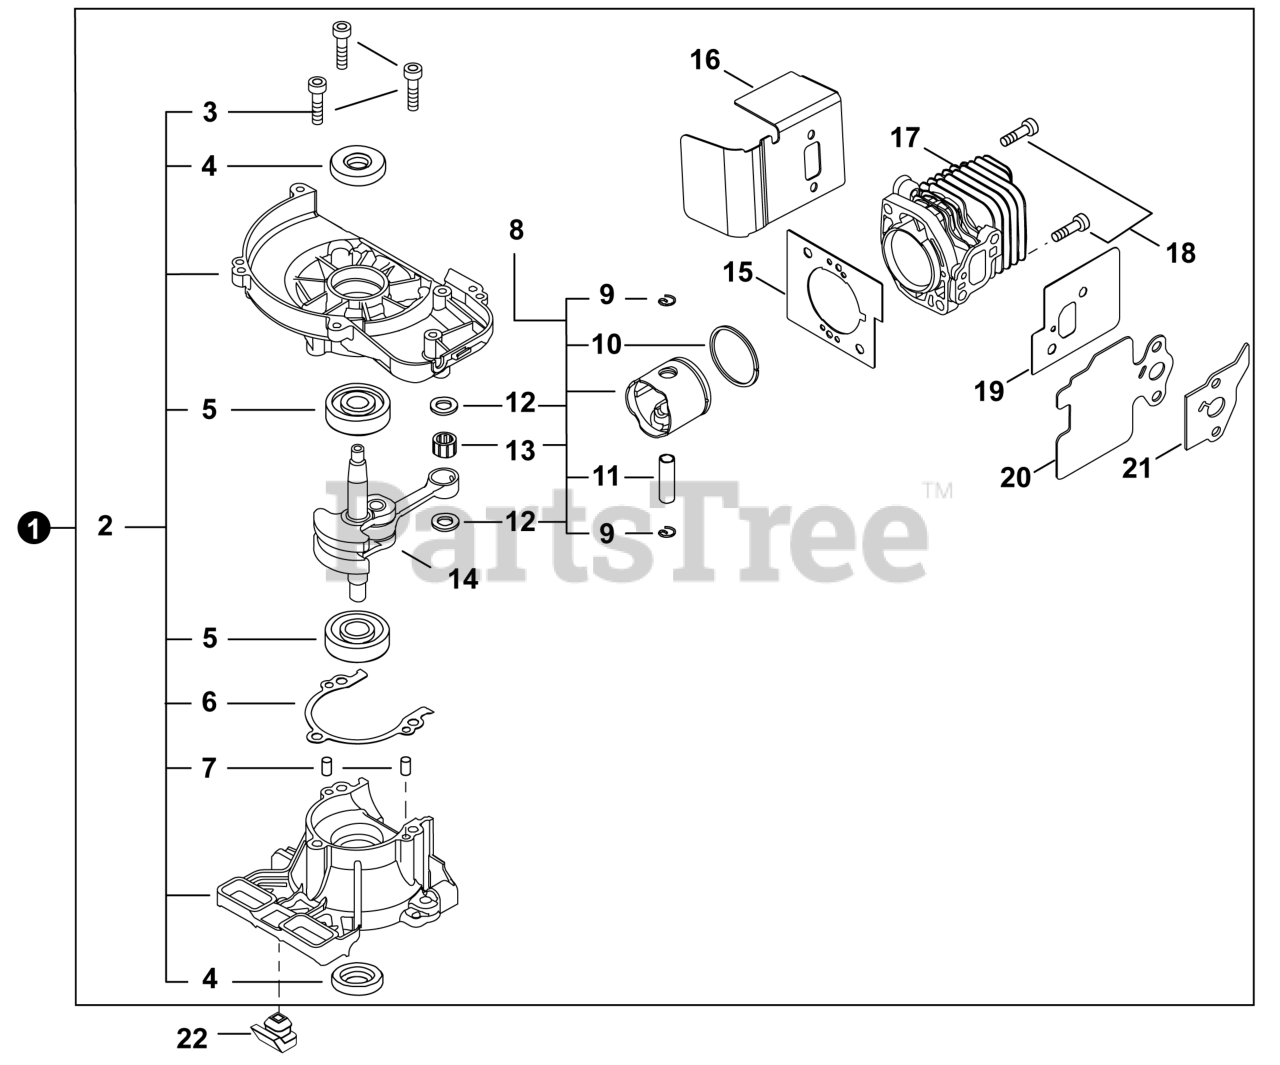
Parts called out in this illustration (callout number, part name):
1	SHORT BLOCK
2	CRANKCASE KIT
3	BOLT 5×28
4	SEAL, OIL
5	BEARING, BALL
6	GASKET, CRANKCASE
7	PIN, LOCATING 4×8
8	PISTON KIT
9	RING, SNAP
10	RING, PISTON
11	PIN, PISTON 8
12	WASHER, THRUST
13	BEARING, NEEDLE
14	CRANKSHAFT ASSY
15	GASKET, CYLINDER
16	HEAT SHIELD, EXHAUST
17	CYLINDER
19	GASKET, INTAKE
20	HEAT SHIELD, INTAKE
21	GASKET, INTAKE
22	CUSHION
